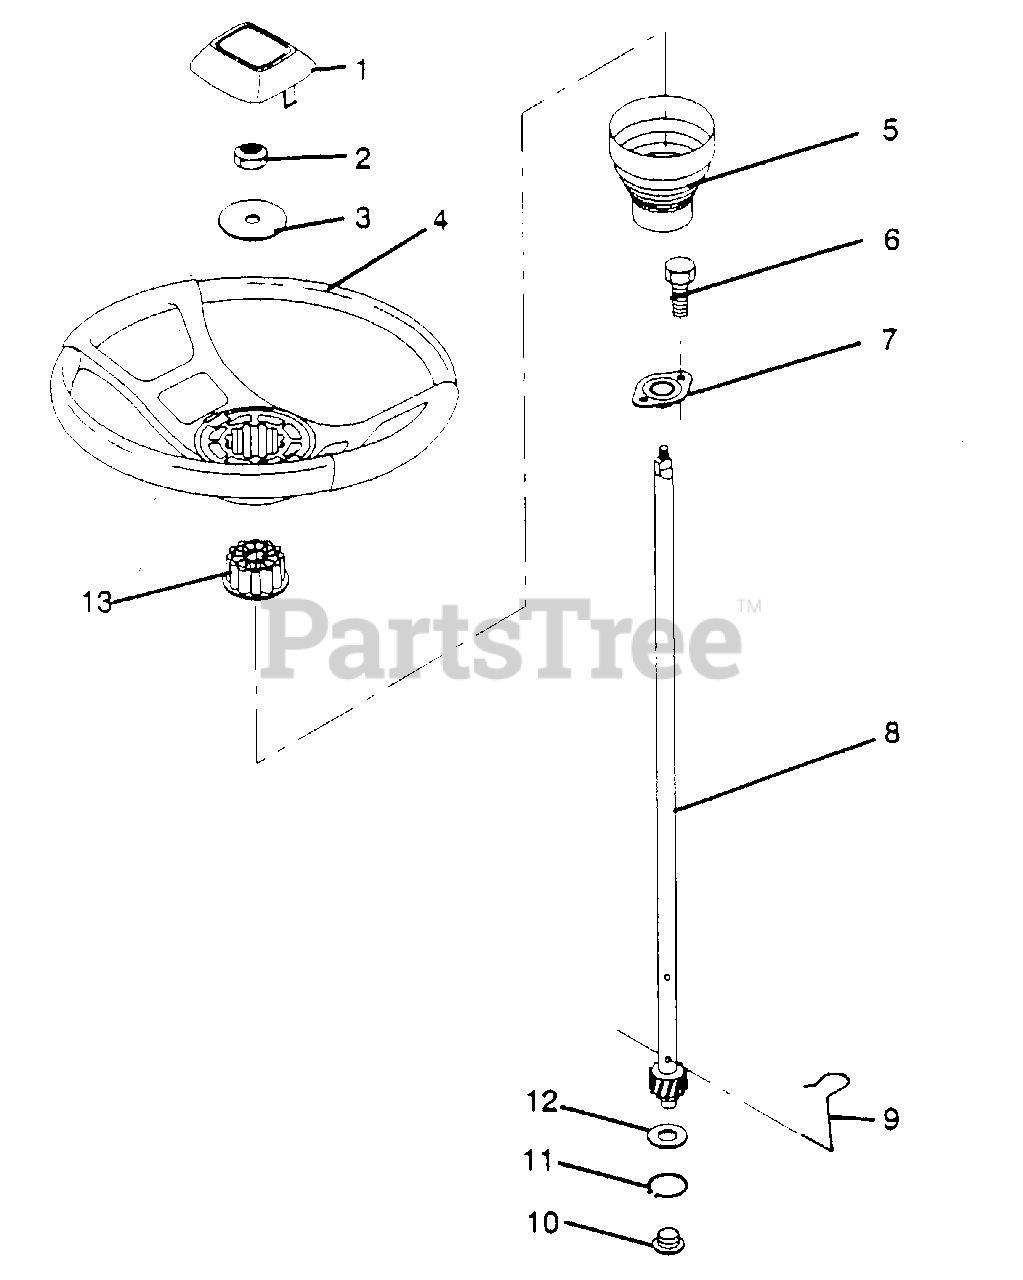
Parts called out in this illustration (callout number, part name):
1	Cap, Wheel, Steering (AYP part number)
2	Nut, Lock 3/8-24 UNF (AYP part number)
3	Washer 13/32 x 2-3/8 x 8 Ga. (AYP part number)
4	Wheel, Steering (AYP part number)
5	Sleeve, Steering (AYP part number)
6	Screw, Hex SLFTP #10-16 x 1/2 TY-B (AYP part number)
7	Bushing, Steering (AYP part number)
8	Shaft, Steering (AYP part number)
9	Clip, Steering (AYP part number)
10	Bushing, Lower, Steering (AYP part number)
11	Ring, Retaining (AYP part number)
12	Washer 21/32 x 1 x 16 Ga. (AYP part number)
13	Adaptor, Wheel, Steering (AYP part number)
